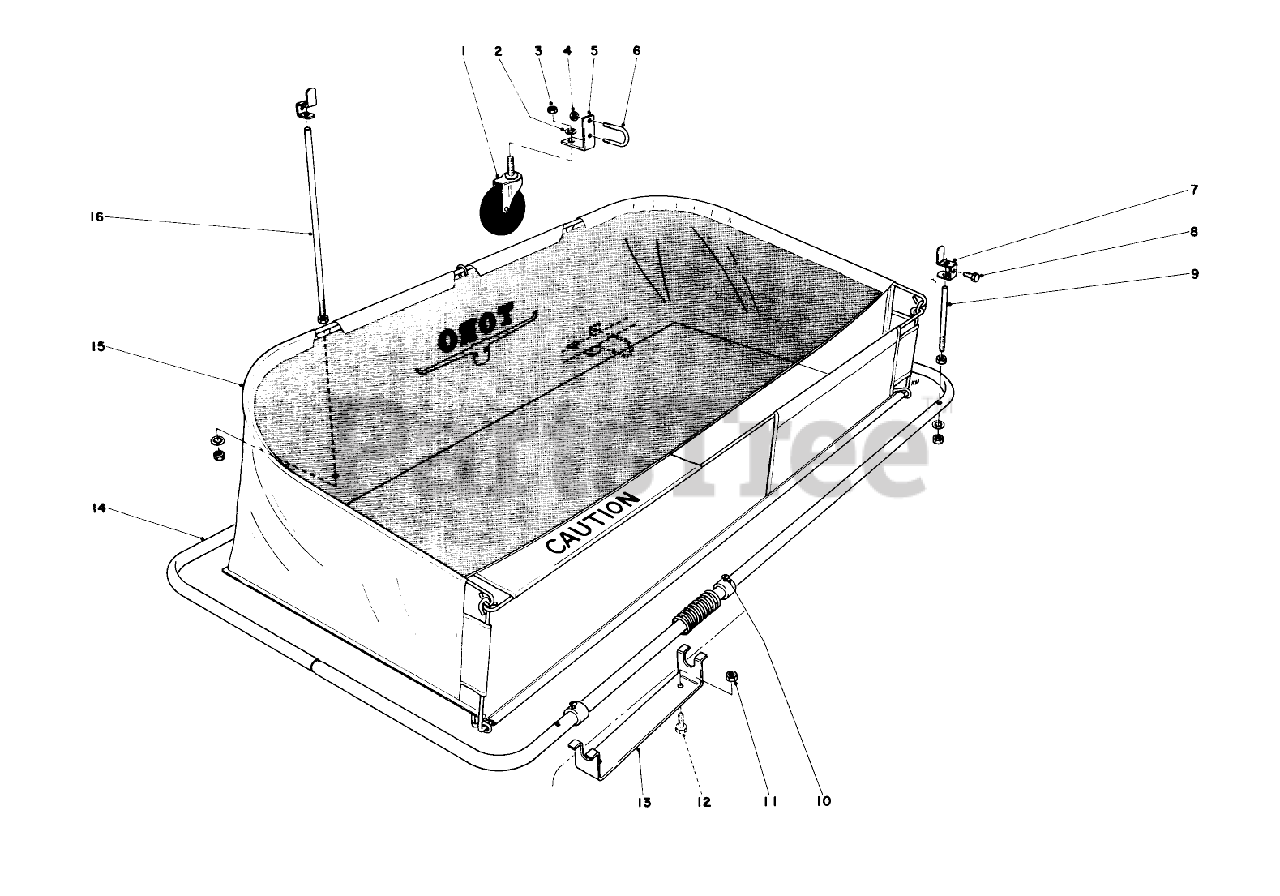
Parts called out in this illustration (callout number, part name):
1	Caster
2	WASHER-LOCK, INTERNAL
3	NUT-HEX
4	NUT-HEX
5	Bracket, Caster
6	U Bolt
8	SCREW-HH
9	Stud, Short
10	Screw, Machine
11	NUT-HEX, SIDE DEFORM
12	SCREW-HH
13	Bracket, Deck Mounting
14	Frame
15	Basket
16	Stud, Long
